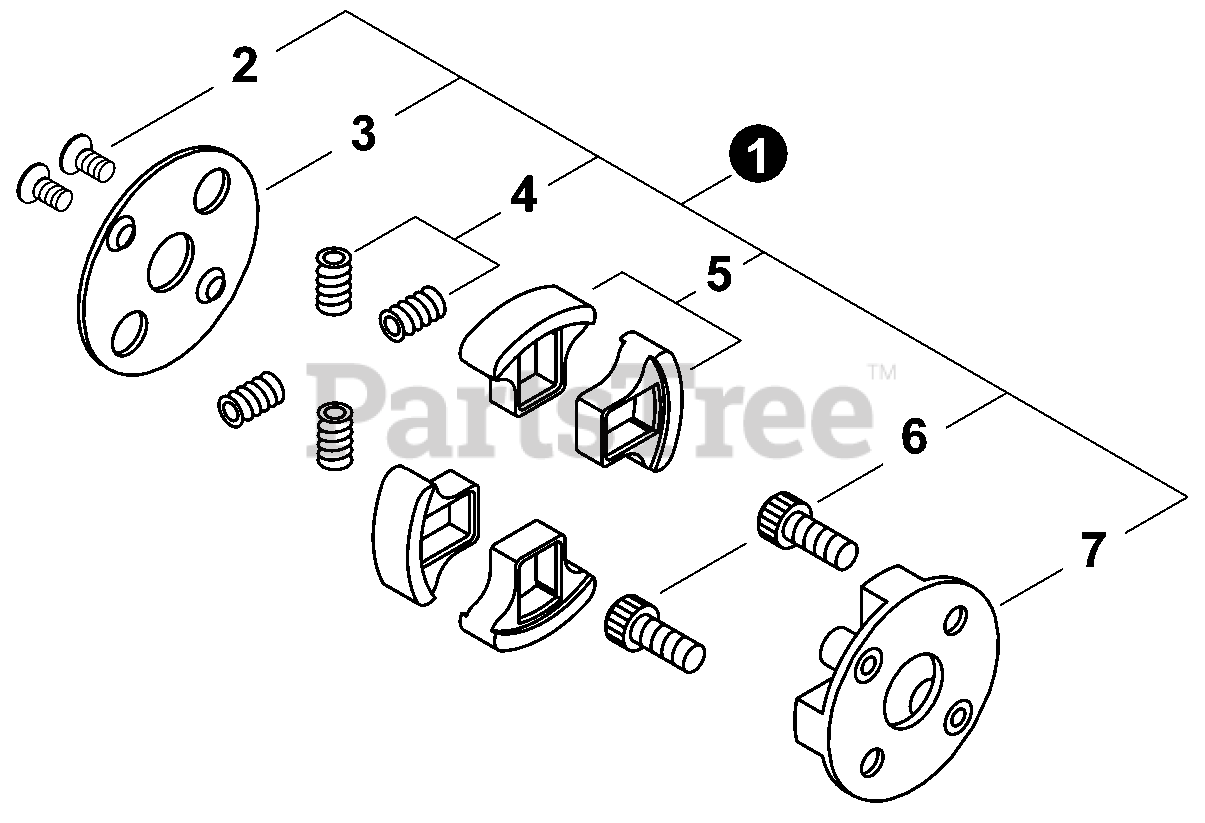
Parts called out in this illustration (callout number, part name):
1	CLUTCH ASSY
2	BOLT 5
3	PLATE, CLUTCH
4	SPRING, CLUTCH
5	SHOE, CLUTCH
6	BOLT, CLUTCH
7	BOSS, CLUTCH
